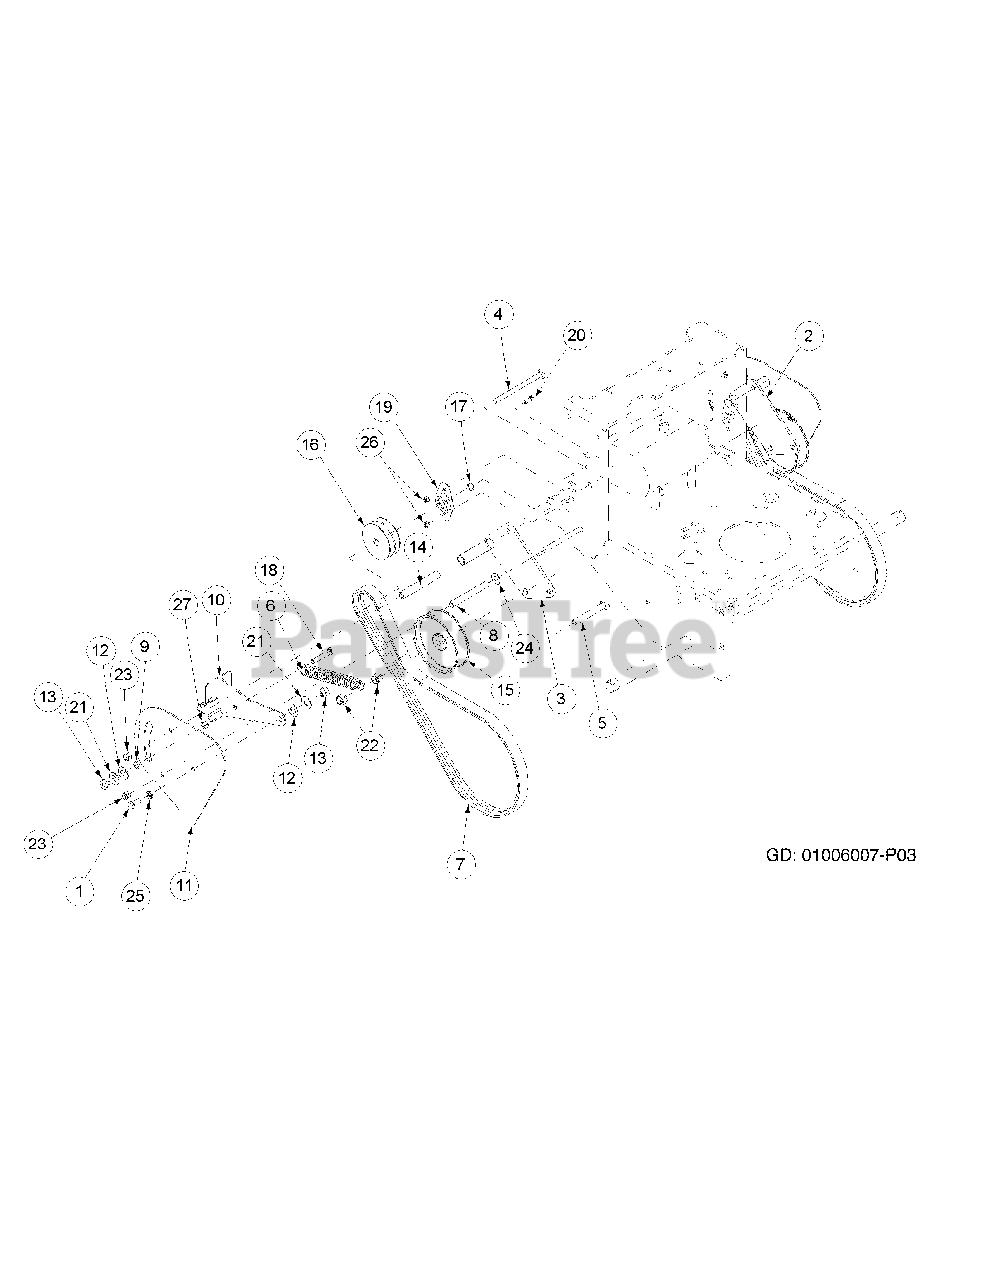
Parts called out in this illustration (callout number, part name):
1	Hex Cap Screw, 3/8-16, .875
2	Left Idler Bracket
3	Right Idler Bracket
4	Carriage Bolt, 3/8-16 x 5.50
5	Hex Cap Screw, 1/2-13, 3.50
6	Extension Spring
8	Spacer Tube
9	Roller Tube
10	Spring Position Adjuster
12	Slide Washer
13	Shoulder Nut
14	Idler Sleeve
15	Flat Idler Drive
16	Jackshaft Pulley
17	External Retain Ring
18	Hex Cap Screw, 3/8-16, 2.00
19	Bearing Housing
20	Carriage Bolt, 1/4-20 x .750
21	Flat Washer, .536 ID x .930 OD x .05
22	Lock Nut, Nylon Insert, 1/2-13
23	Lock Nut, Nylon Insert, 3/8-16
24	Flat Washer, 3/8 Zinc
25	Lock Washer, 3/8 Zinc
26	Lock Nut, Nylon Insert, 1/4-20
27	Hex Nut, 3/8-16
